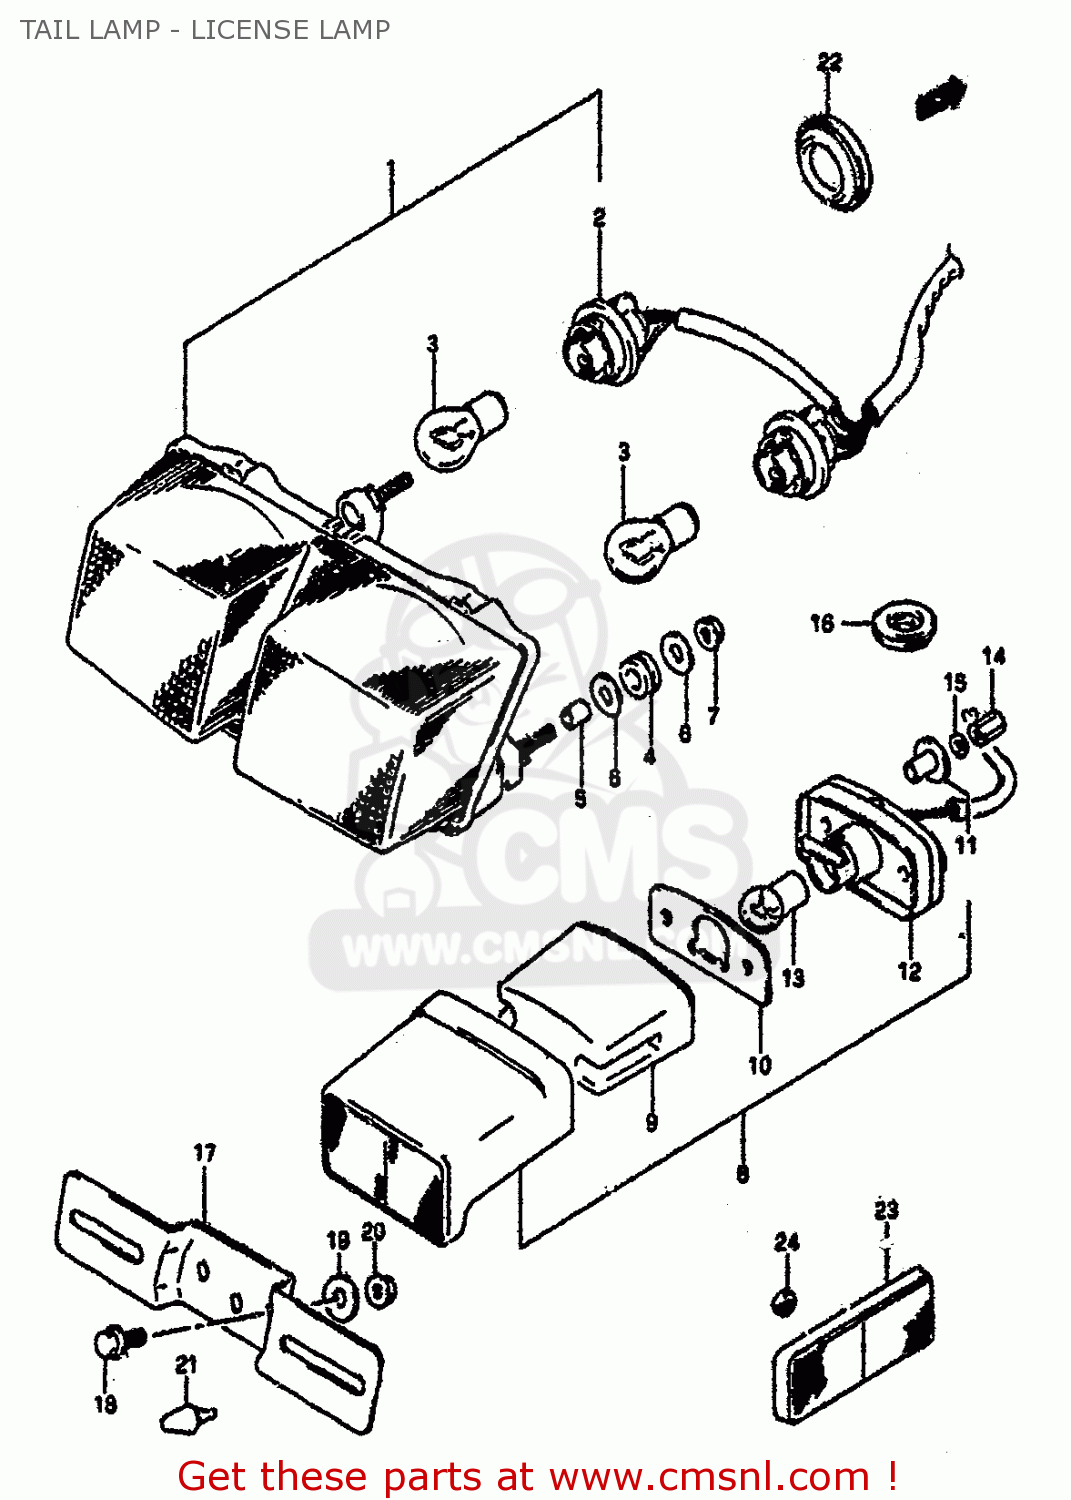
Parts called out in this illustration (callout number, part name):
1	LAMP,REAR COMB
2	SOCKET ASSEMBLY
3	BULB(12V21/5W)
4	CUSHION
5	SPACER (6.1X8X9.5)
6	WASHER(6.5X18X1)
7	NUT
8	LAMP ASSY,LICE
9	LENS
10	GASKET,LICENSE LAMP (NAS)
11	SPACER
12	HOUSING
13	BULB(12V5W,BF150-40160A)
14	NUT
15	LOCK WASHER
16	GROMMET
17	BRACKET,LICENSE PLATE
18	BOLT
19	WASHER,COVER,FRONT
20	NUT
21	CUSHION
22	CAP OD:40
23	REFLEX REFLECTOR,FR SIDE
24	NUT 5MM
